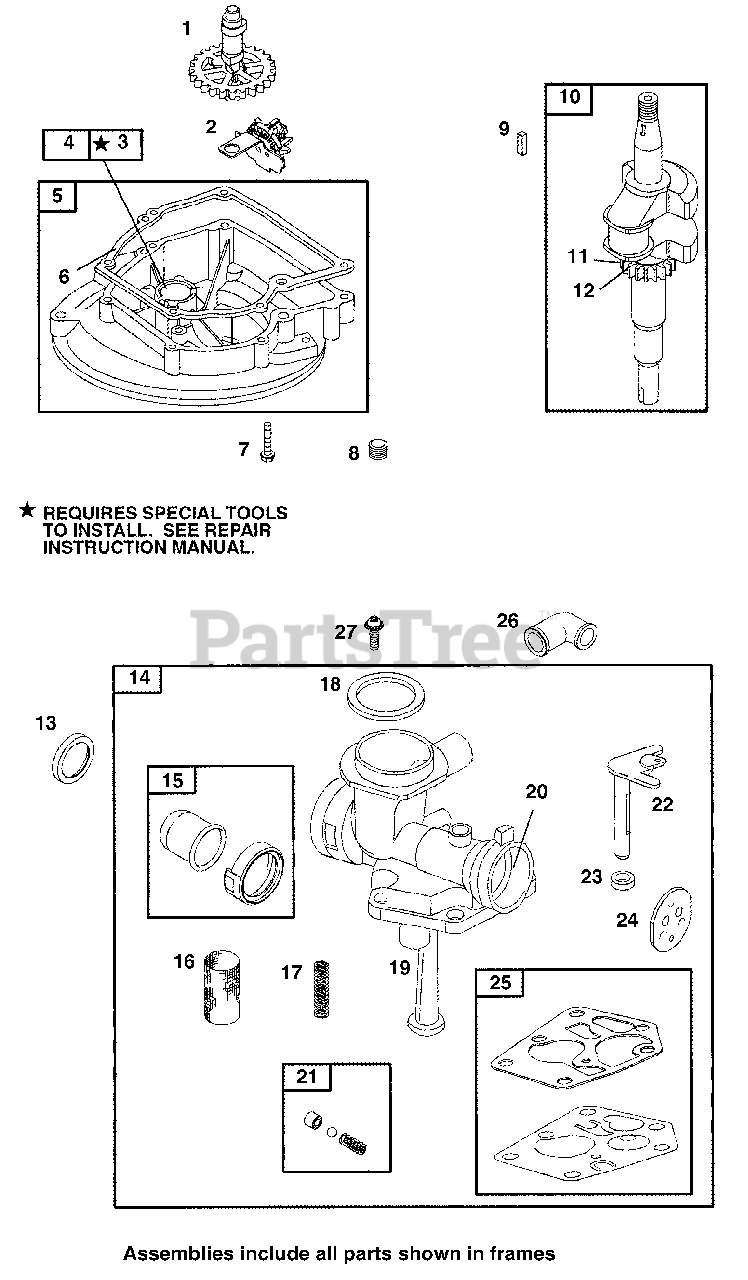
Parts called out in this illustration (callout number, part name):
1	Cam Gear (Clockwise)
2	Oil Slinger/Governor
4	Oil Seal
5	Engine Sump
6	Crankcase Gasket (Standard)
7	Hex Screw
8	Oil Drain Plug
9	Flywheel Key
10	Crankshaft
11	Timing Key
12	Timing Gear
13	Trim Ring (Primer Bulb)
14	Carburetor
15	Carburetor Primer
16	Carburetor Screen
17	Choke Diaphragm Spring
18	Air Cleaner Gasket
19	Pickup Tube
20	Intake Manifold Seal
21	Check Valve Seat
22	Throttle Shaft
24	Throttle Valve
25	Carburetor Diaphragm
26	Grommet
27	Screw Phillips
